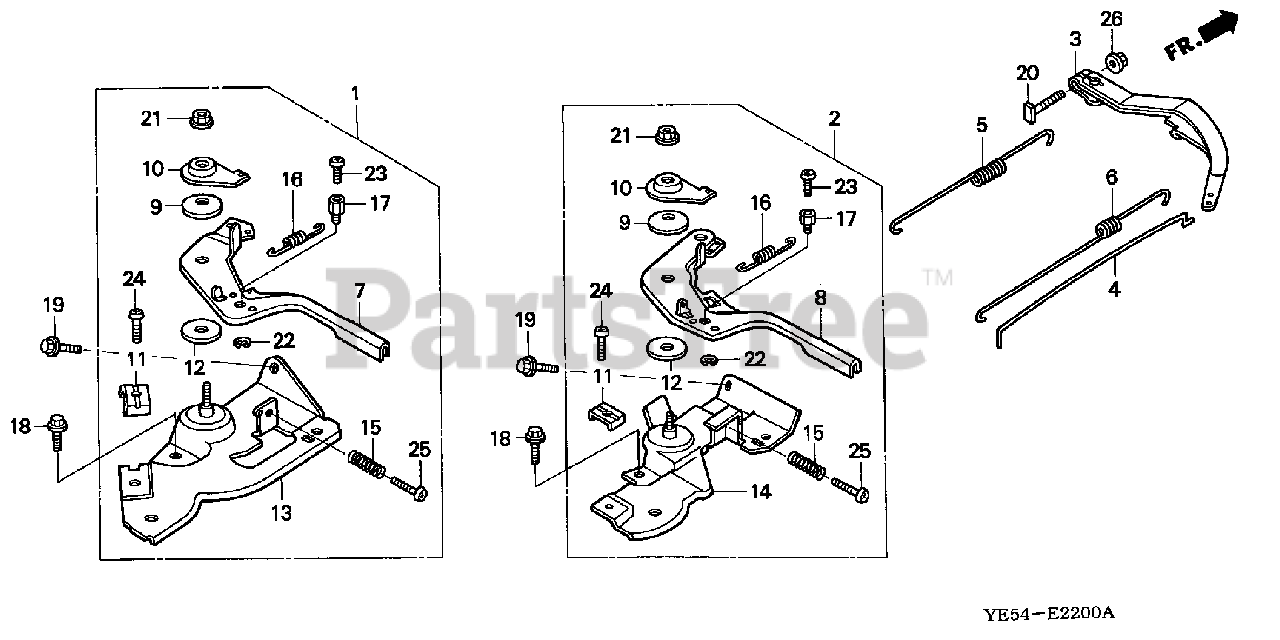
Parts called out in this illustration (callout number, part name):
1	CONTROL ASSY. (REMOTE)
3	ARM, GOVERNOR
4	ROD, GOVERNOR
5	SPRING, GOVERNOR
6	SPRING, THROTTLE RETURN
7	LEVER, CONTROL
9	SPRING, LEVER
10	WASHER, CONTROL LEVER
11	HOLDER, CABLE
12	SPACER, CONTROL LEVER
13	BASE, CONTROL
15	SPRING, CONTROL ADJUSTING
16	SPRING, CABLE RETURN
17	HOLDER, WIRE
18	BOLT, FLANGE (6X12) (CT200)
19	BOLT, FLANGE (6X20) (CT200)
20	BOLT, GOVERNOR ARM
21	NUT, SELF-LOCK (6MM)
22	CIRCLIP (5MM)
23	SCREW, PAN (4X6)
24	SCREW, PAN (5X16)
25	SCREW, PAN (5X25)
26	NUT, FLANGE (6MM)
